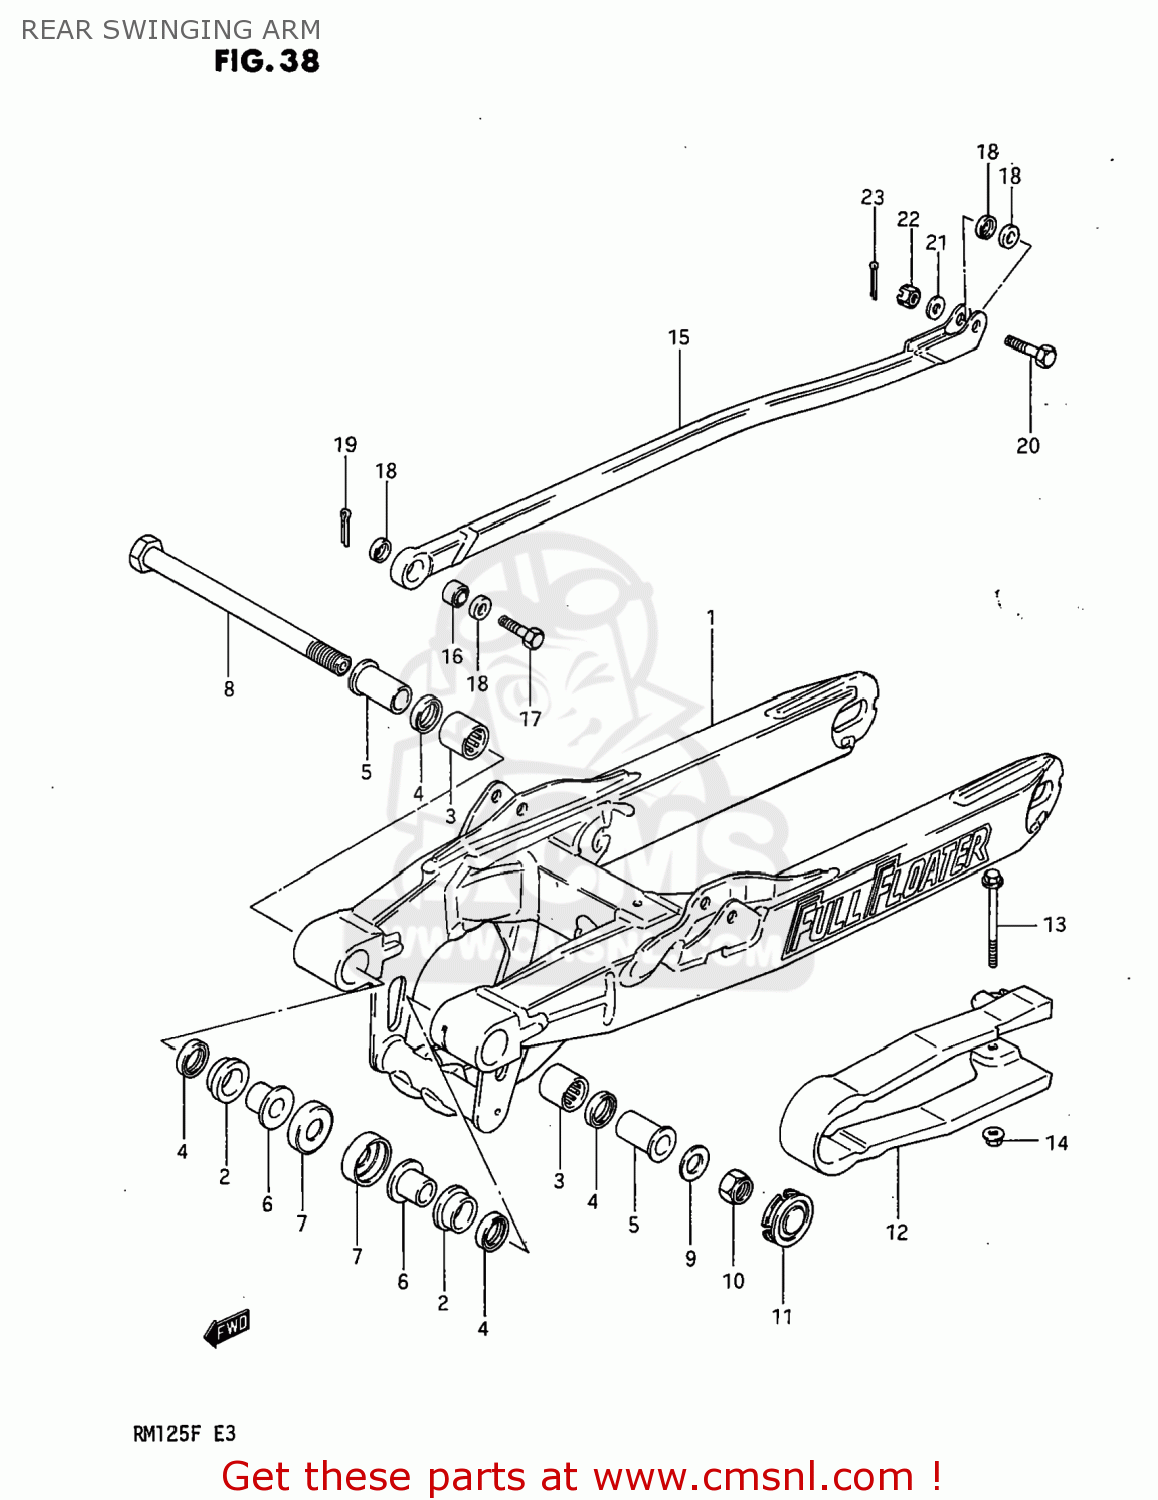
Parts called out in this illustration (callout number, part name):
1	SWING ARM ASSEMBLY,REAR
2	BUSH,RR SWINGINGARM PIVOT
3	BEARING(20X27X20)
4	OIL SEAL
5	SPACER,RR SWGARM PIVOT
6	SPACER,RR SWGARM PIVOT INNER
7	COVER,RR SWGARM DUST SEAL
8	SHAFT,REAR SWING ARM
9	WASHER(14.2X24X2.3)
10	NUT
11	CAP
12	BUFFER,CHAIN TOUCH DEFENSE
13	BOLT (6X70)
14	NUT
15	LINK,REAR TORQUE
16	SPHERICAL BEARING,TORQUE
17	BOLT 8X28
18	19
19	PIN
20	BOLT 8X29.5
21	WASHER
22	NUT 8MM
23	PIN 20X20
